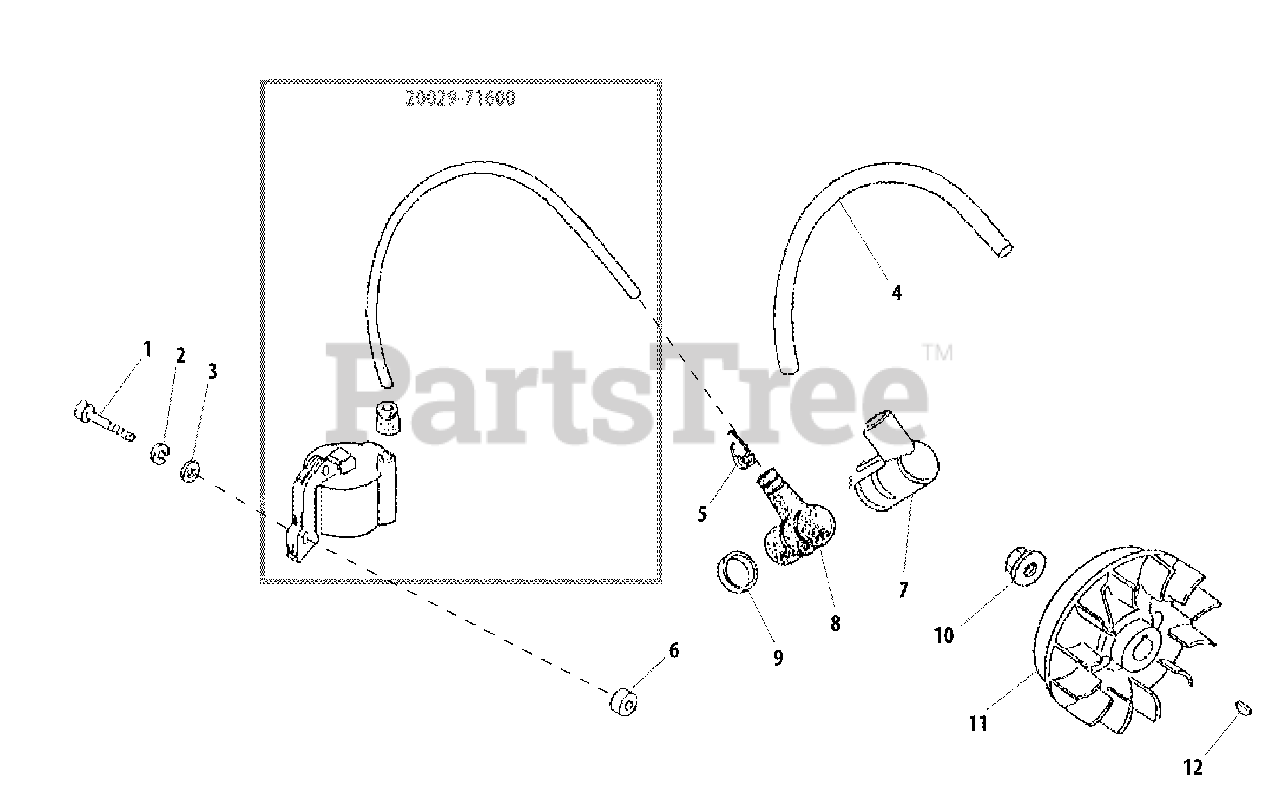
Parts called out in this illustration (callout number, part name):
1	BOLT
2	WASHER, SPRING 4 MM
3	WASHER 4 MM
4	TUBE
5	TERMINAL, SPARK PLUG
6	INSULATOR 4.2×11×6
7	COVER, CAP
8	CAP, SPARK PLUG
9	SEAL, SPARK PLUG
10	NUT M8
11	FLYWHEEL
12	KEY, WOODRUFF 3×10
A	COIL, IGNITION
